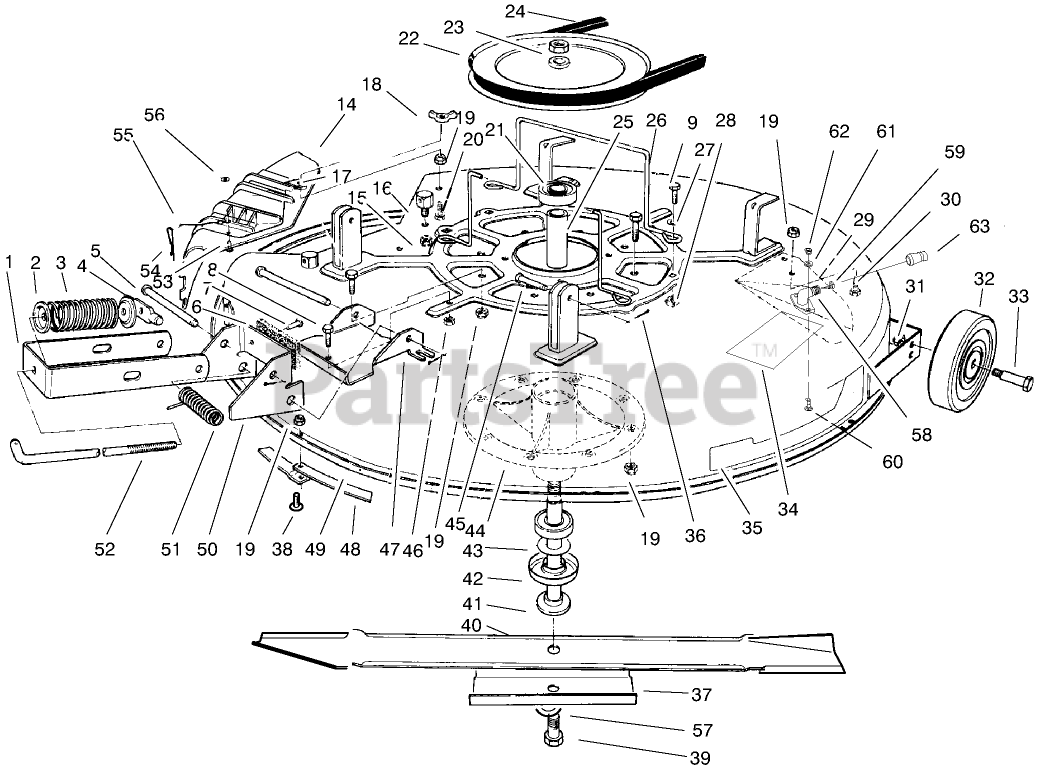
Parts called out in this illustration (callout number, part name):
2	RETAINER-SPR. TOP
3	SPRING-COMPRESSION
4	SHAFT-DECK ADJ.
5	PIN-CLEVIS
6	PAD-BRAKE
7	RIVET-BLIND
8	SCREW-HH
9	SCREW-HH
16	POST-PIVOT
18	NUT-WING
19	NUT-LOCK, NI
20	SCREW-HH
21	BEARING-BALL
22	PULLEY
23	NUT-HEX
24	V-BELT, DECK
25	SPACER-BEARING
26	GUIDE-BELT
27	WASHER-PLAIN
28	NUT-RETAINER
30	SCREW-HH
31	NUT-LOCK, NI
32	WHEEL-DECK
34	DECAL-DANGER, THROWN OBJECT
36	PIN-COTTER
38	SCREW-PPH
39	SCREW-HH
41	SHAFT-SPINDLE
42	SHIELD-BEARING
43	SPACER-HARDNED
44	SPINDLE
45	PIN-CLEVIS
46	NUT-HEX
49	DECK ASM-32", DOM
51	SPRING
52	ROD-ENGAGEMENT
53	RIVET-BLIND
54	PIN-LOCKING, CHUTE
55	LANYARD
56	WASHER-PLAIN
57	WASHER-BELLEVILLE
59	O-RING
60	BOLT-CARR
61	WASHER-FLAT
62	NUT-LOCK, NI
63	CONNECTOR-HOSE
